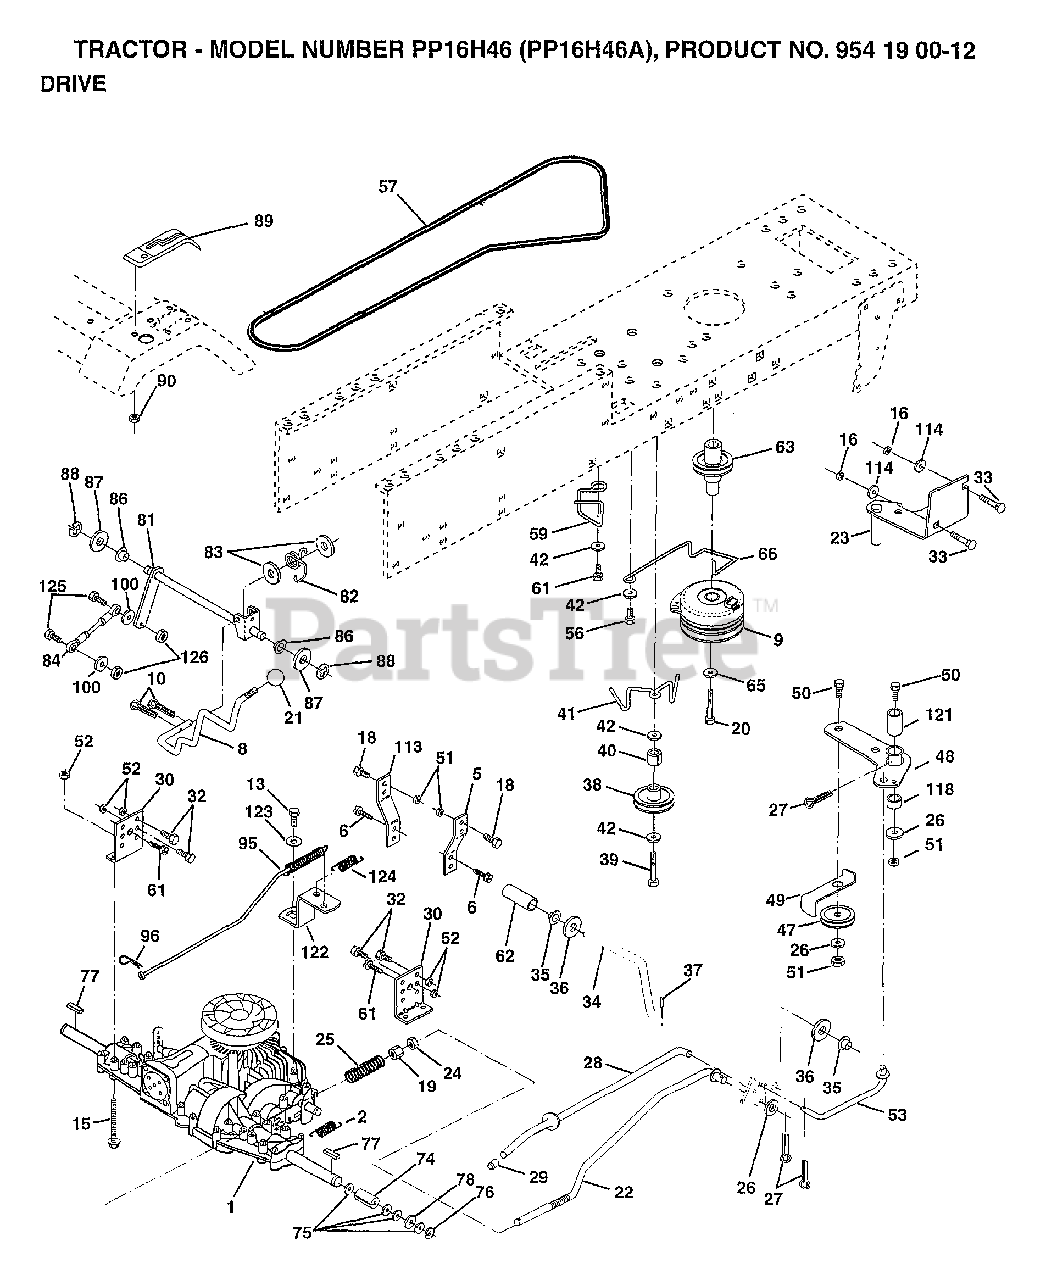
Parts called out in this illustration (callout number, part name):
2	SPRING.BRAKE.RETU
3	PULLEY.TRANSAXLE
5	STRAP TORQUE
6	SCREW
8	"ROD SHIFT,FENDER"
9	CLUTCH.ELECT.EVX.
10	PIN COTTER 1/8
13	BOLT.1/4-28.W/PAT
15	BOLT.HX.FLG.5/16
16	NUT
18	BOLT
19	NUT
20	BOLT.7/16-20X4.25
21	KNOB.DUCKHEAD.1/2
22	BRAKE ROD
23	BRACKET.CLUT.MTG.
24	NUT
25	SPRING ROD LT
26	WASHER
27	COTTER PIN
28	ROD.BRAKE.PARK.LT
29	PLUNGER CAP T
30	TRANSAXLE MTG BKT
32	BOLT
33	BOLT
34	SHAFT ASM-PEDAL F
35	NYLON BEARING
36	WASHER LT
38	PULLEY.IDLER.FLAT
39	BOLT
40	SPACER T
42	WASHER
48	BELLCRANK ASM
49	RETAIN BELT
53	"LINK, CLUTCH T"
55	"SPRING, RETURN LT"
57	"V-BELT,GRD DRIVE"
59	KEEPER BELT CNTSP
61	SCREW
62	PEDAL COVER T
63	PULLEY.CLUTCH.EVX
65	LOCKWASHER
66	KEEPER-BELT
74	"SPACER AXLE,PVST"
75	WASHER
76	E-RING LT
77	SQUARE KEY
78	WASHER
81	SHAFT ASM CROSS
82	"SPRING,TORSION"
83	WASHER
84	"ROD TIE, PVST 20"""
86	BUSHING
87	WASHER D
88	KLIP RING
90	NUT
95	ROAD ASM BYPASS
96	RETAINER M
100	WASHER M
113	"STRAP,TORQUE"
114	WASHER
118	SPACER-BELLCRANK
121	NYLINER-CLUTCHING
122	"PLATE-BYPASS,PVST"
123	WASHER
